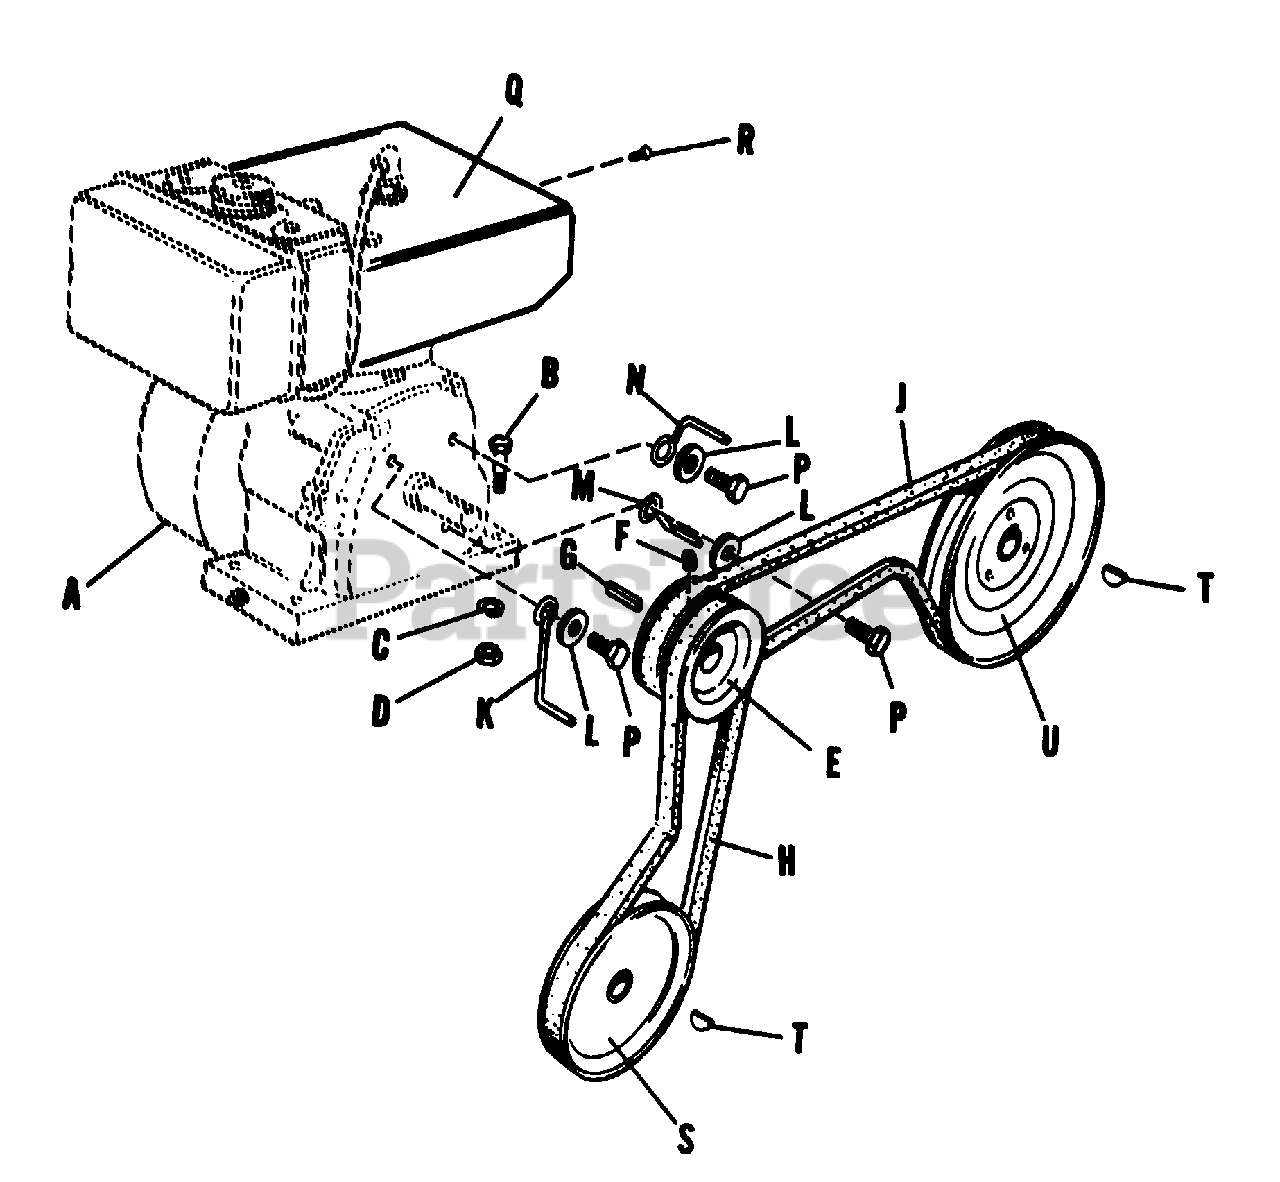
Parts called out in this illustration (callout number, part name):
B	Capscrew, Hex, 5/16"-18 NC x 1-1/2" lg.
C	Washer, Lock, 5/16"
D	Hex Nut, Full, 5/16"-18 NC
E	Pulley, Engine
F	Set Screw, Socket Hd., 5/16"-18 NC x 3/8" lg.
G	Key, Square
H	Belt, "V" (Rotor Drive)
J	Belt, "V" (Transmission Drive)
K	Stop, Belt
L	Washer, Plain, 5/16"
M	Stop, Belt
N	Stop, Belt
P	Capscrew, Hex, 5/16"-24 NF x 5/8" lg.
Q	Deflector, Hot Air
R	Machine Screw, Round Hd., #10-32 NF x 1/2" lg.
T	Key, Woodruff
U	Pulley, Transmission Drive
